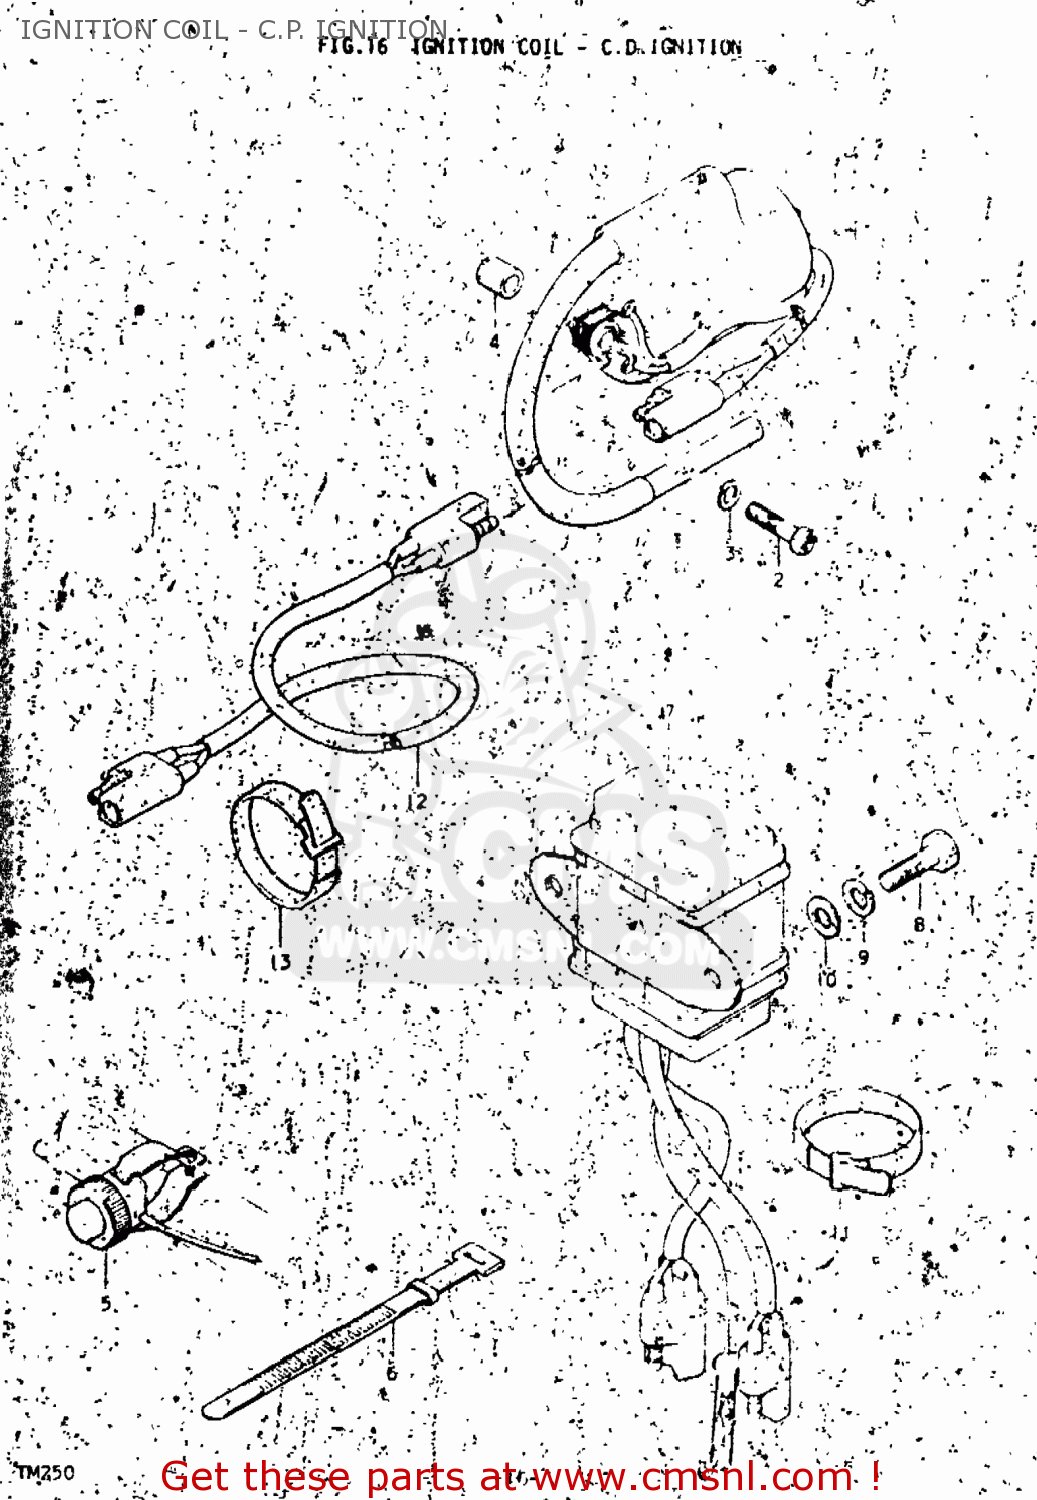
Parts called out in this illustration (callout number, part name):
1	COIL ASSEMBLY,IGNITION
2	SCREW
3	LOCK WASHER
4	SPACER
5	SWITCH ASSEMBLY
6	CLAMP
7	C.D. IGNITION UNIT
8	BOLT(6X20)
9	LOCK WASHER
10	WASHER
11	CLAMP
13	CLAMP
